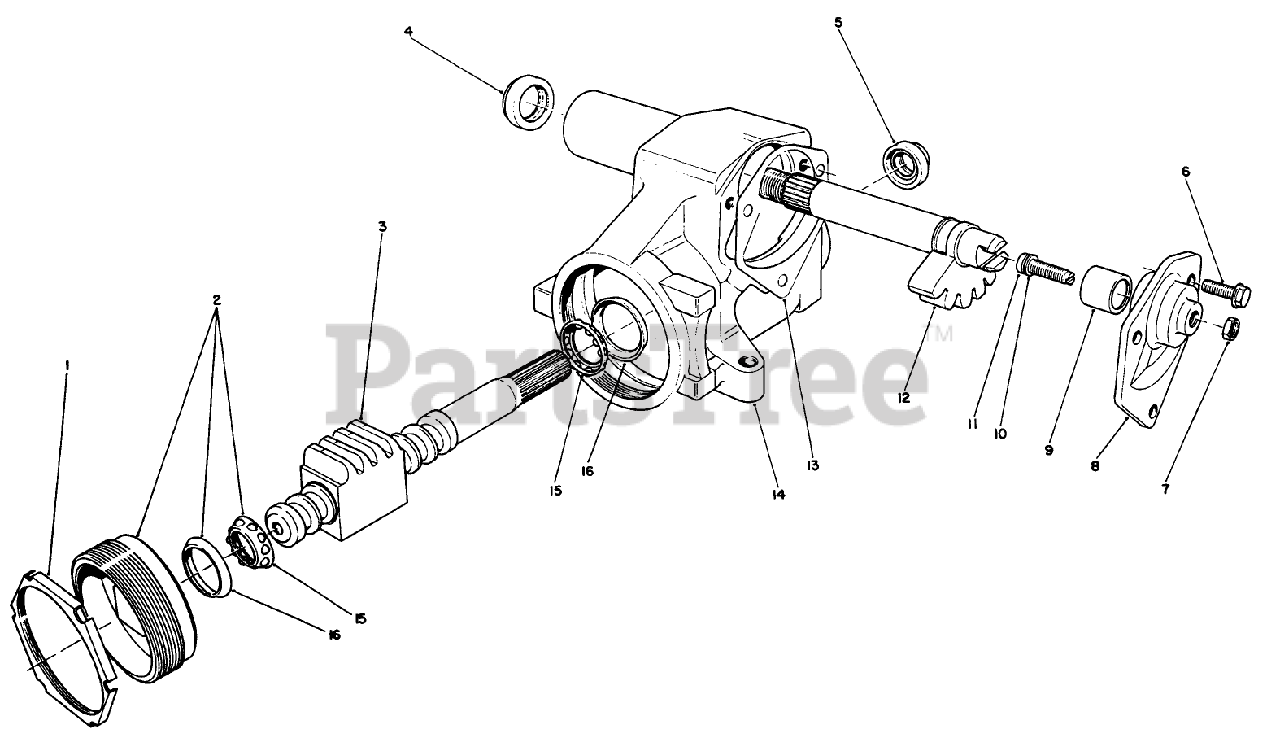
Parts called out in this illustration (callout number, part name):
1	Nut-Adjuster Lock
2	Assembly-Adjuster
3	Steering Worm Assembly
6	Bolt-Flange Hex. Hd.
8	Kit-Side Cover Service (Incl. Ref. #6, 9, 11 & 13)
10	Kit-Shim
11	Adjuster
12	Gear-Pitman Shaft
13	Gasket
14	Housing-Steering Gear
15	Assembly-Thrust Bearing
16	Cup-Bearing
